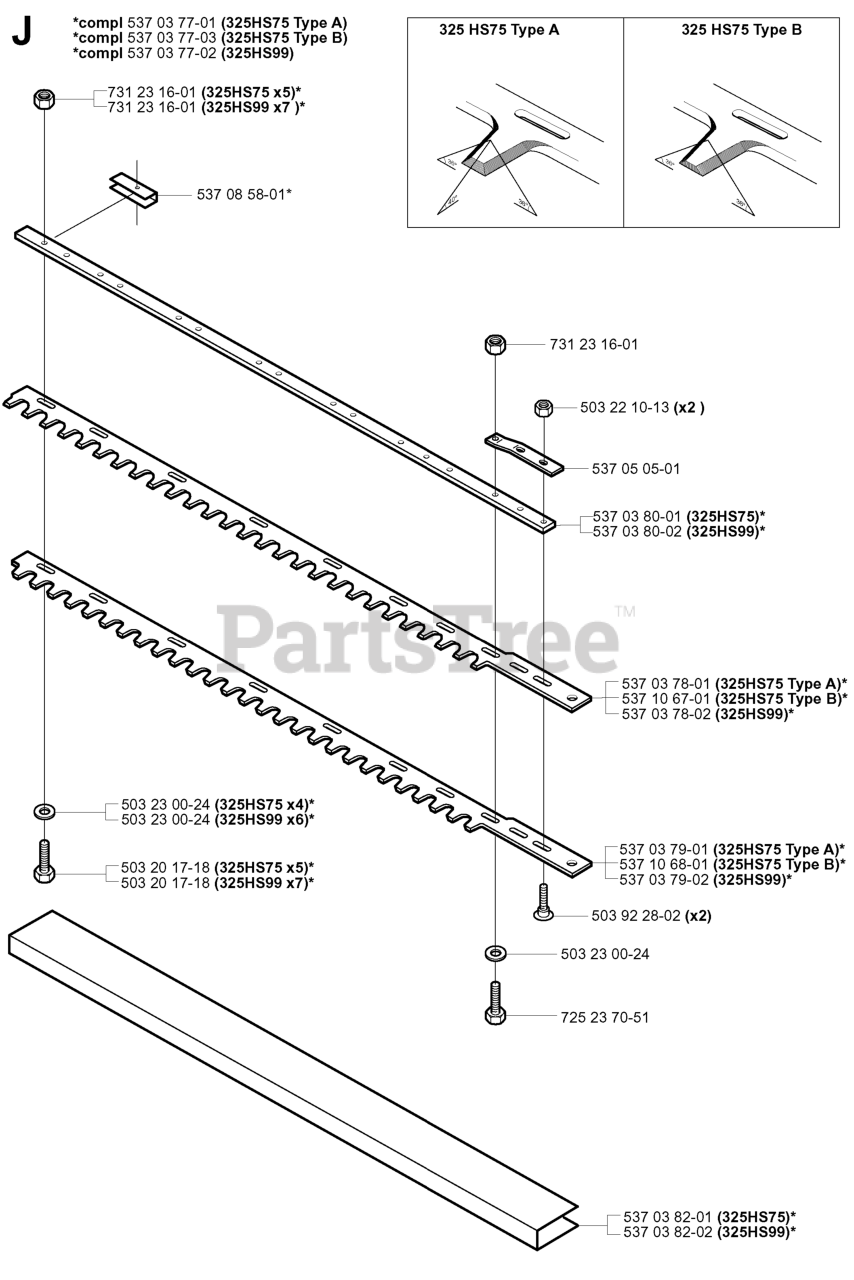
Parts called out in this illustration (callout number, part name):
1	WASHER, HARD, M10, ZN-NI/BLK
2	BOLT, M10 X 45, ZN-NI/BLK
3	BRACKET, SEAT BELT, BENCH
4	ASM SEAT BOTTOM BENCH
5	HINGE PLATE
7	BOLT FLG BLK, M8 X 25, LOCTITE
8	BRACKET, SEAT BACK, AWD
9	SEAT BACK, BENCH
10	ASM SEAT BOTTOM BENCH BLACK
11	HINGE PLATE
13	BOLT FLG BLK, M8 X 25, LOCTITE
14	SEAT BACK, BENCH, BLACK
15	NUT, FLANGED, M10 X 1.5, BLACK
16	BOLT, M8 X 55, FLANGED, BLACK
